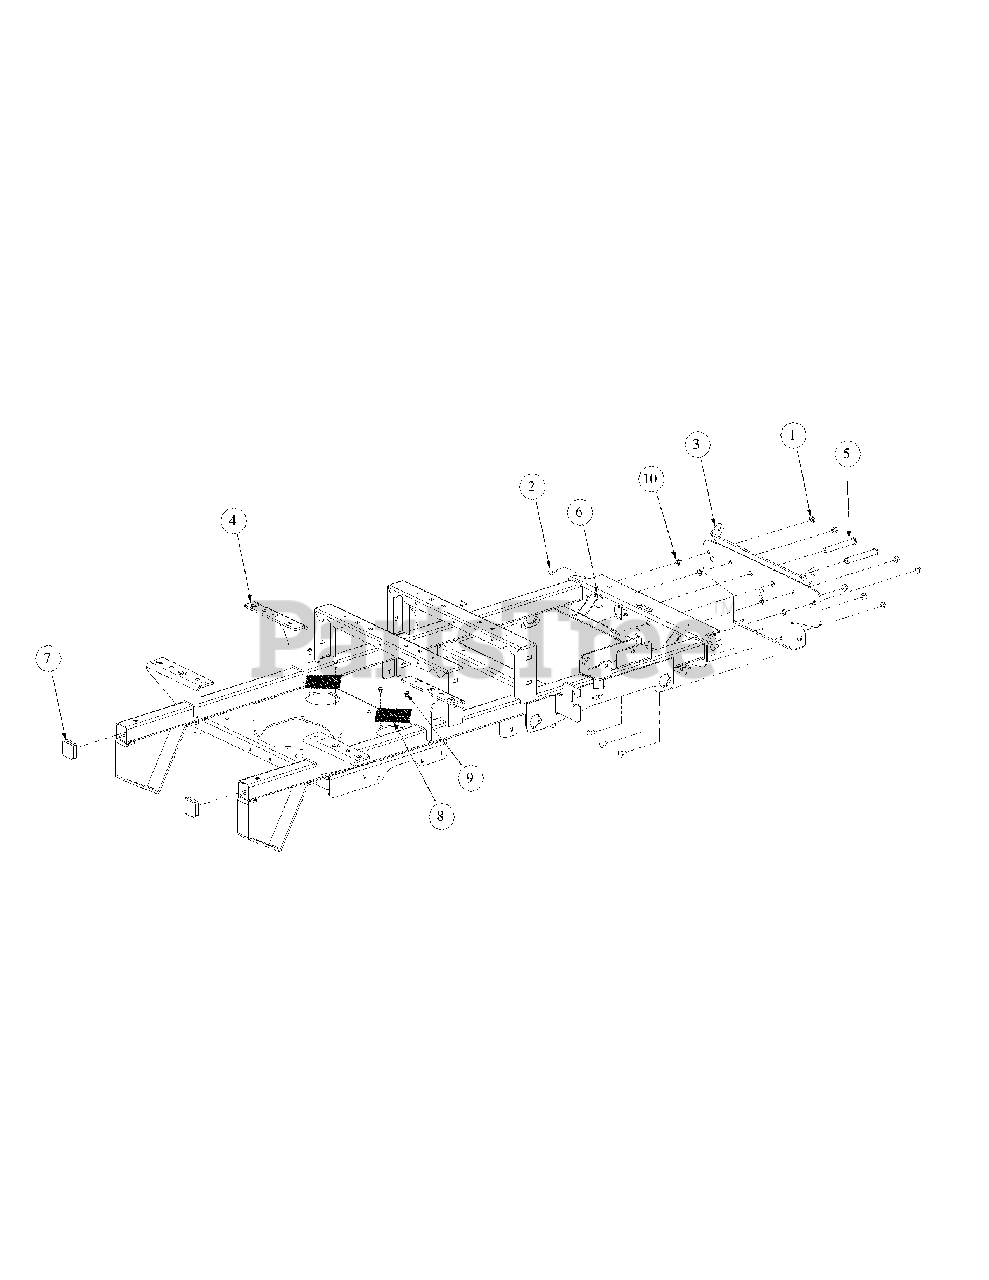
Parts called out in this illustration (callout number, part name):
1	Hex Nut, 3/8-16 Flange Lock
2	Carriage Bolt, 3/8-16 x .75 Long
3	Bracket Assembly, Frame, Front
4	Frame Assembly
5	Clevis Pin,.625 Dia x 4.375 Long
6	Linch Pin, 3/16 Dia.
7	Plug, Square Tube
8	Cover, Hydro Fan
9	Screw, TT, 1/4-20, 0.5
10	Push Retainer, 3/8"-Thread Stud
